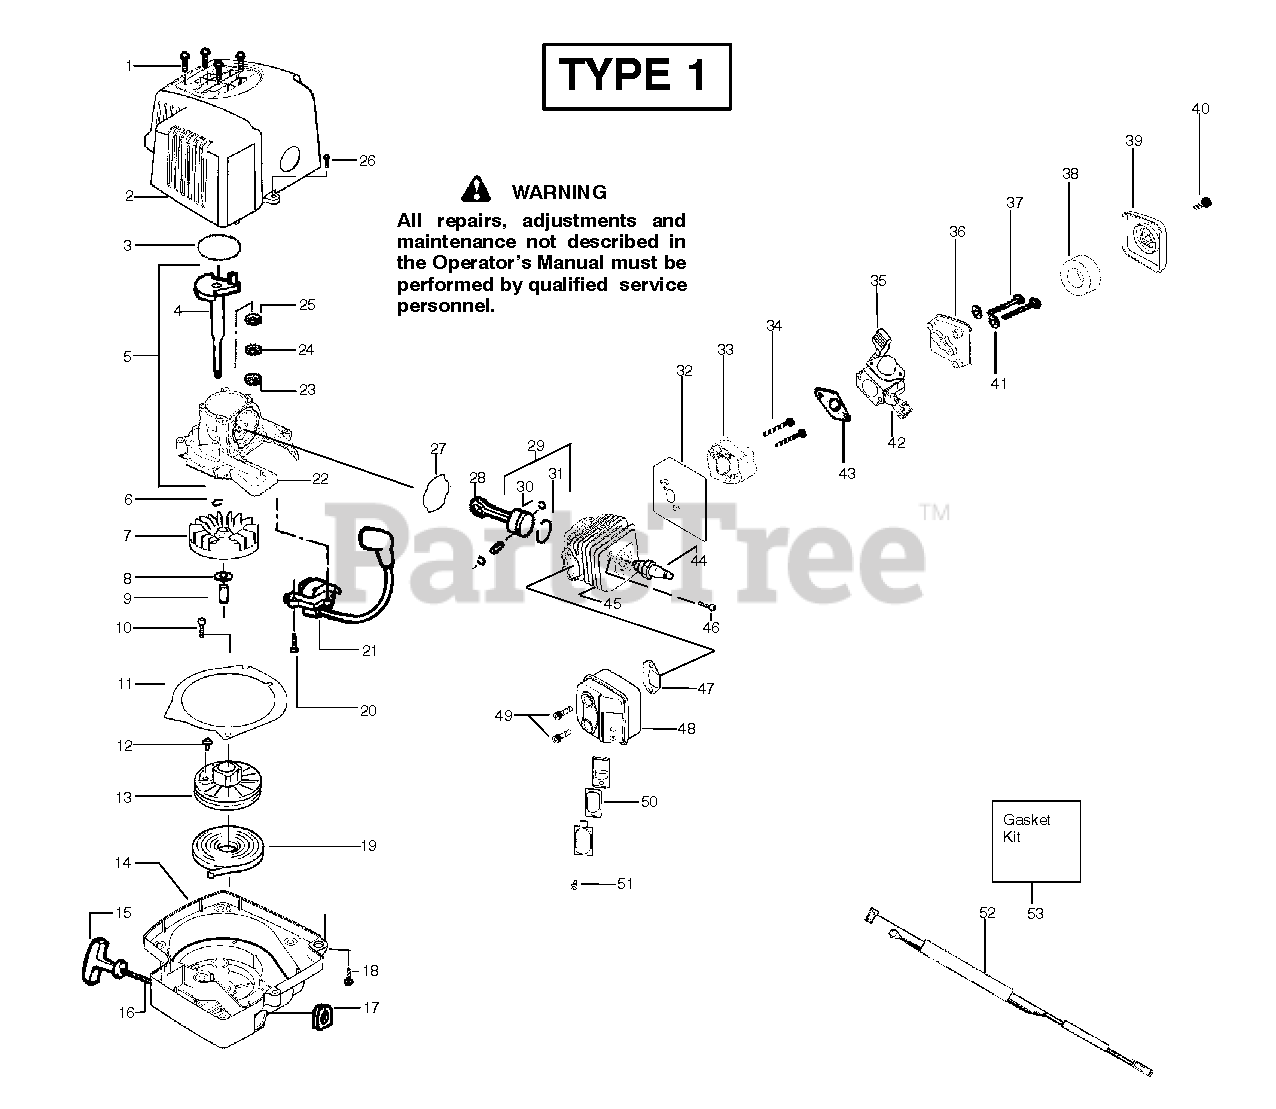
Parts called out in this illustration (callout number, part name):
2	ASSY SHROUD/HEAT SHIELD
3	GASKET KIT
4	CRANKSHAFT ASSY
5	CRANKCASE
6	RETAINING RING
7	FLYWHEEL
8	WASHER FLAT
10	SCREW-10-16 X 1/2 HI-LO
11	PLATE-BAFFLE
12	SCREW SEMS TOOTHED WASHER
13	STARTER PULLEY
14	ASSY FAN HSG W/ EYELET
15	HANDLE-STARTER
16	KIT-ROPE
18	SCREW
19	STARTER SPRING
21	IGNITION MODULE
22	CRANKCASE
23	OUTER BEARING
25	BEARING
27	GASKET KIT
28	KIT-CONN ROD ASSY
29	PISTON
30	WRIST PIN RET.
31	RING-PISTON
32	GASKET KIT
35	CHOKE CONTROL
38	AIR FILTER FOAM
39	AIR FILTER COVER
41	WASHER
42	CARBURETOR ASSY (C1U-W13A)
43	GASKET KIT
44	PLUG-SPARK (RCJ-6Y)
45	CYLINDER
47	GASKET KIT
48	KIT
49	SCREW MUFFLER
50	PARTITION
51	SCREW-6-19X5/16PLAST PA
52	LEAD WIRE
53	GASKET KIT
